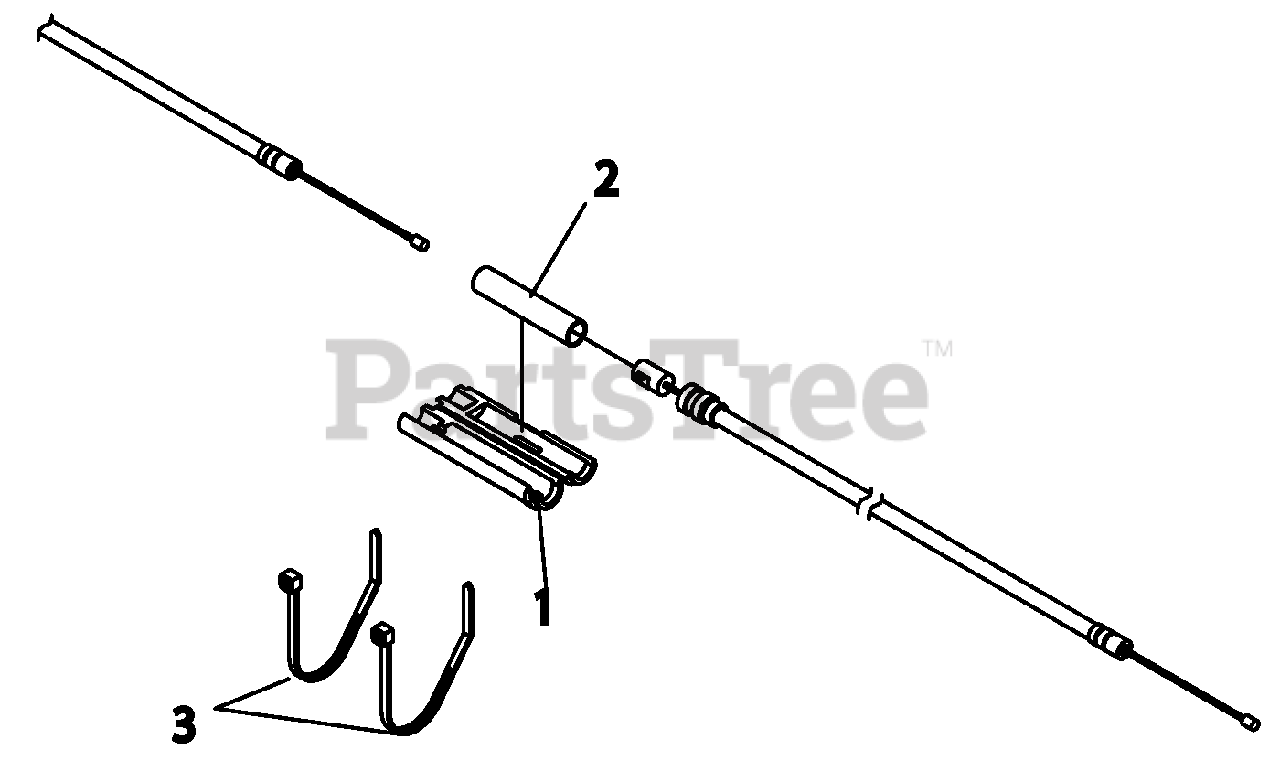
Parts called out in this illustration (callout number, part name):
1	CONNECTOR TUBE
2	SLEEVE
3	TIE, CABLE
